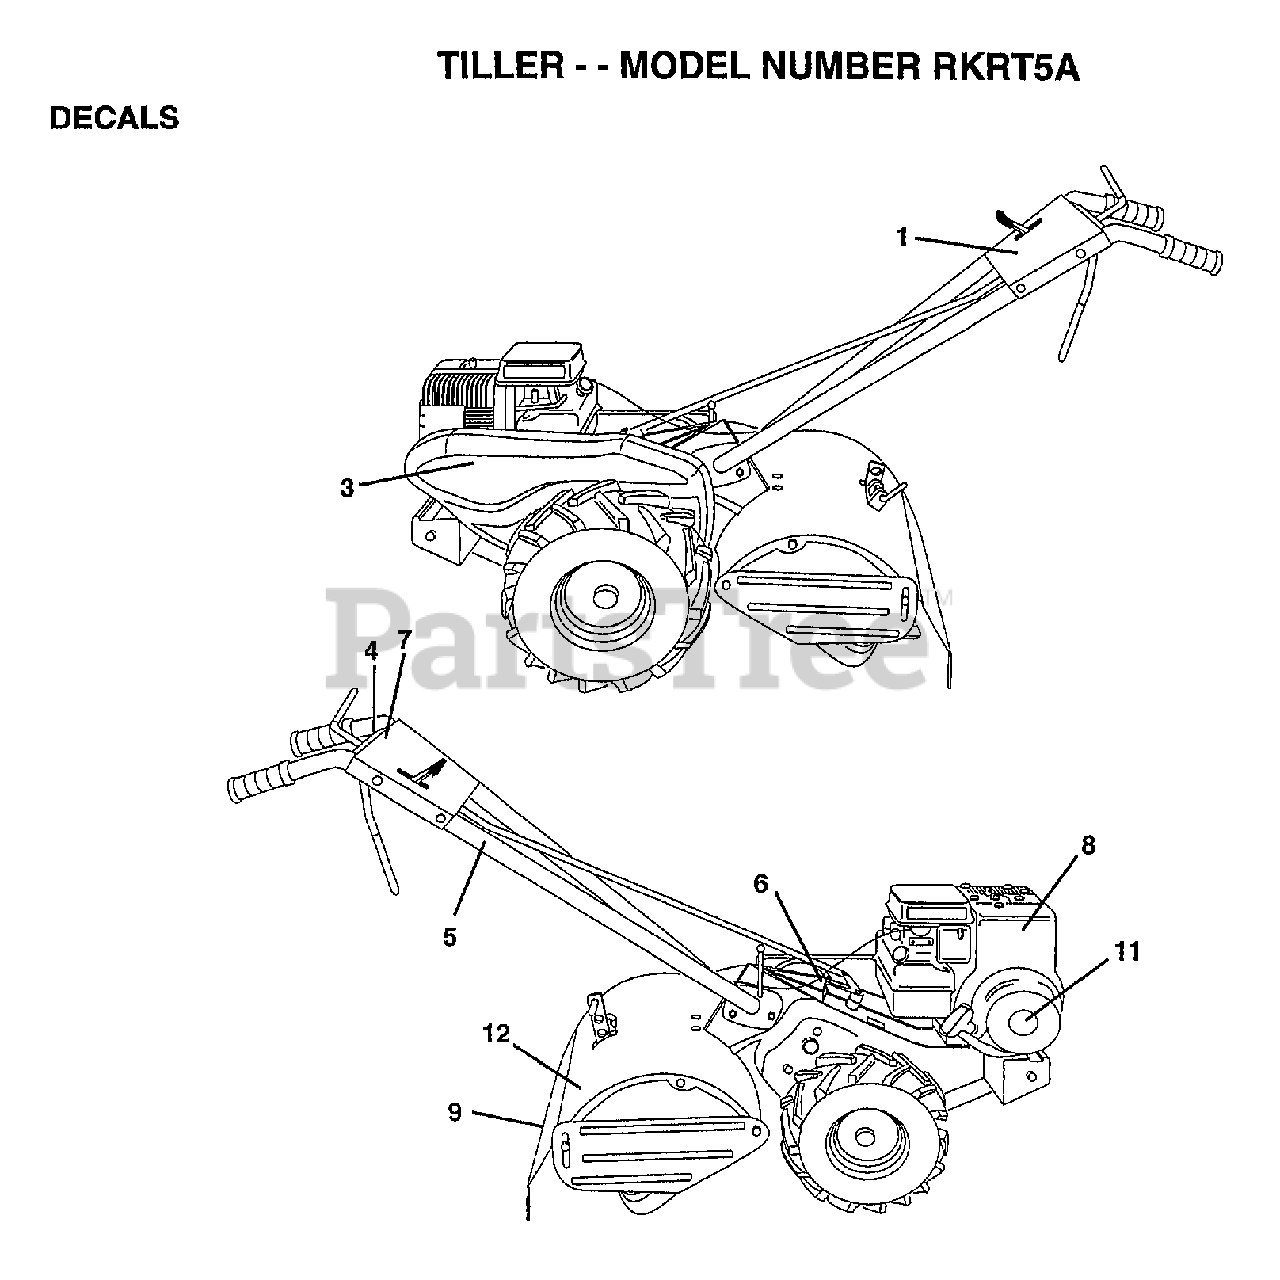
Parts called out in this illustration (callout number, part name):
1	DECAL, LOGO
3	DECAL, LOGO
5	DECAL TI
6	DECAL CRT
7	DECAL REVERSE
12	DECAL.CAUTION
